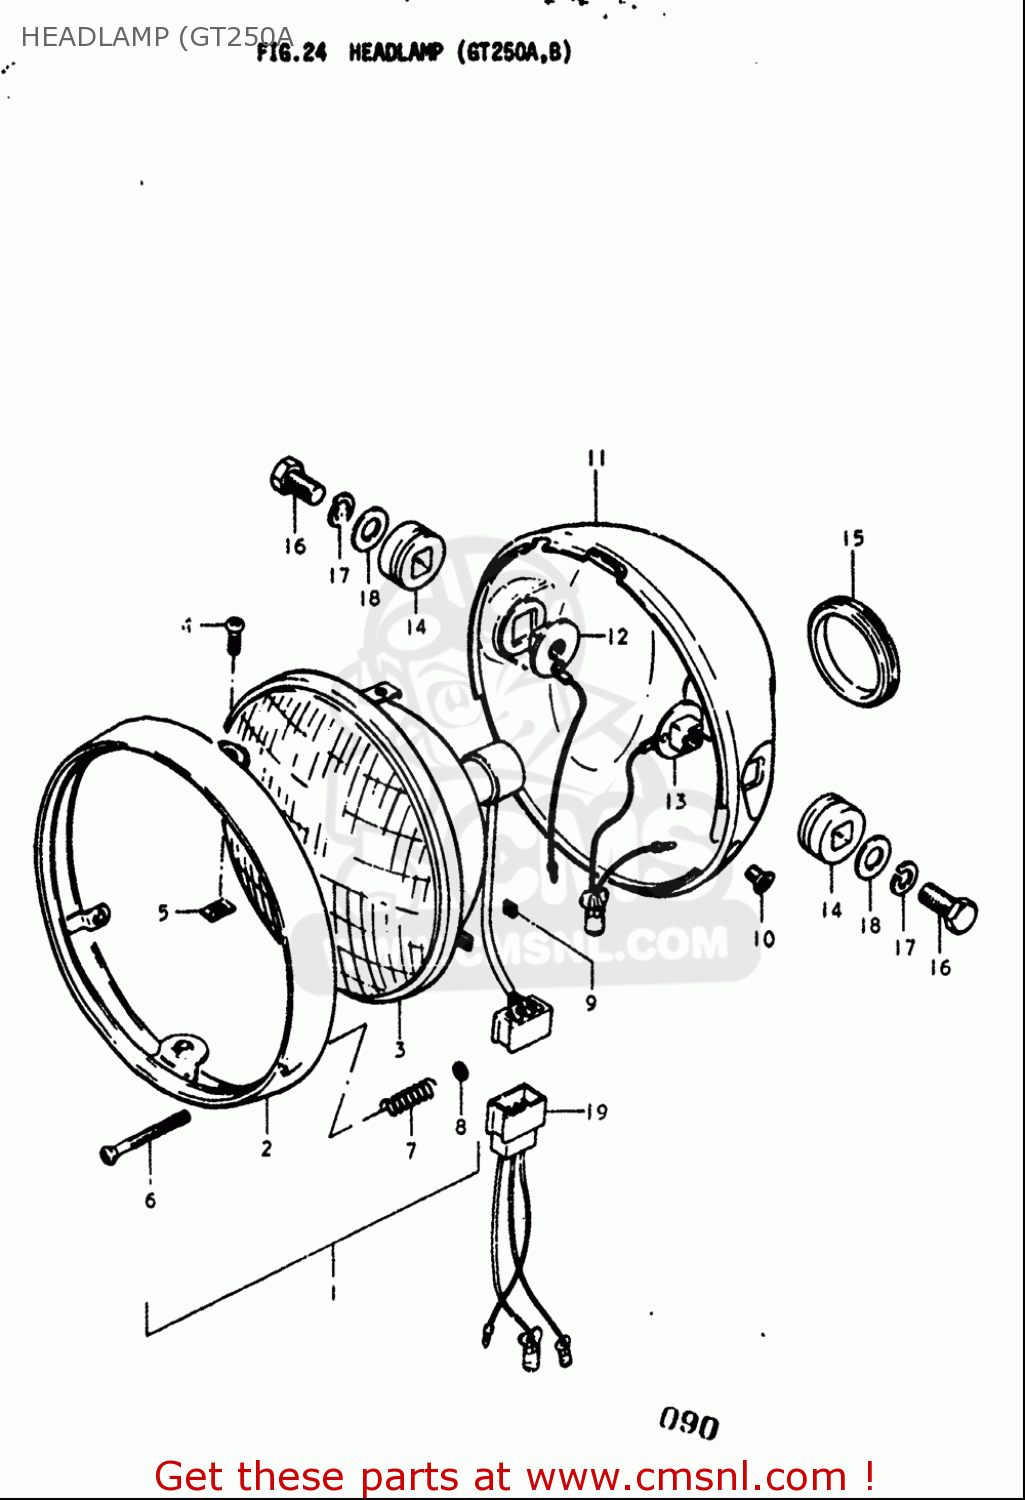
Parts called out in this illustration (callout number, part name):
4	SCREW
5	NUT
6	SCREW
7	SPRING,HEADLAMP ADJUST
8	WASHER
9	NUT
10	SCREW
14	CUSHION,HEADLAMP HOUSING
15	GROMMET,HEADLAMP HOUSING
16	BOLT
17	WASHER,LOCK
18	WASHER
19	WIRE,HEADLAMP GROUND
